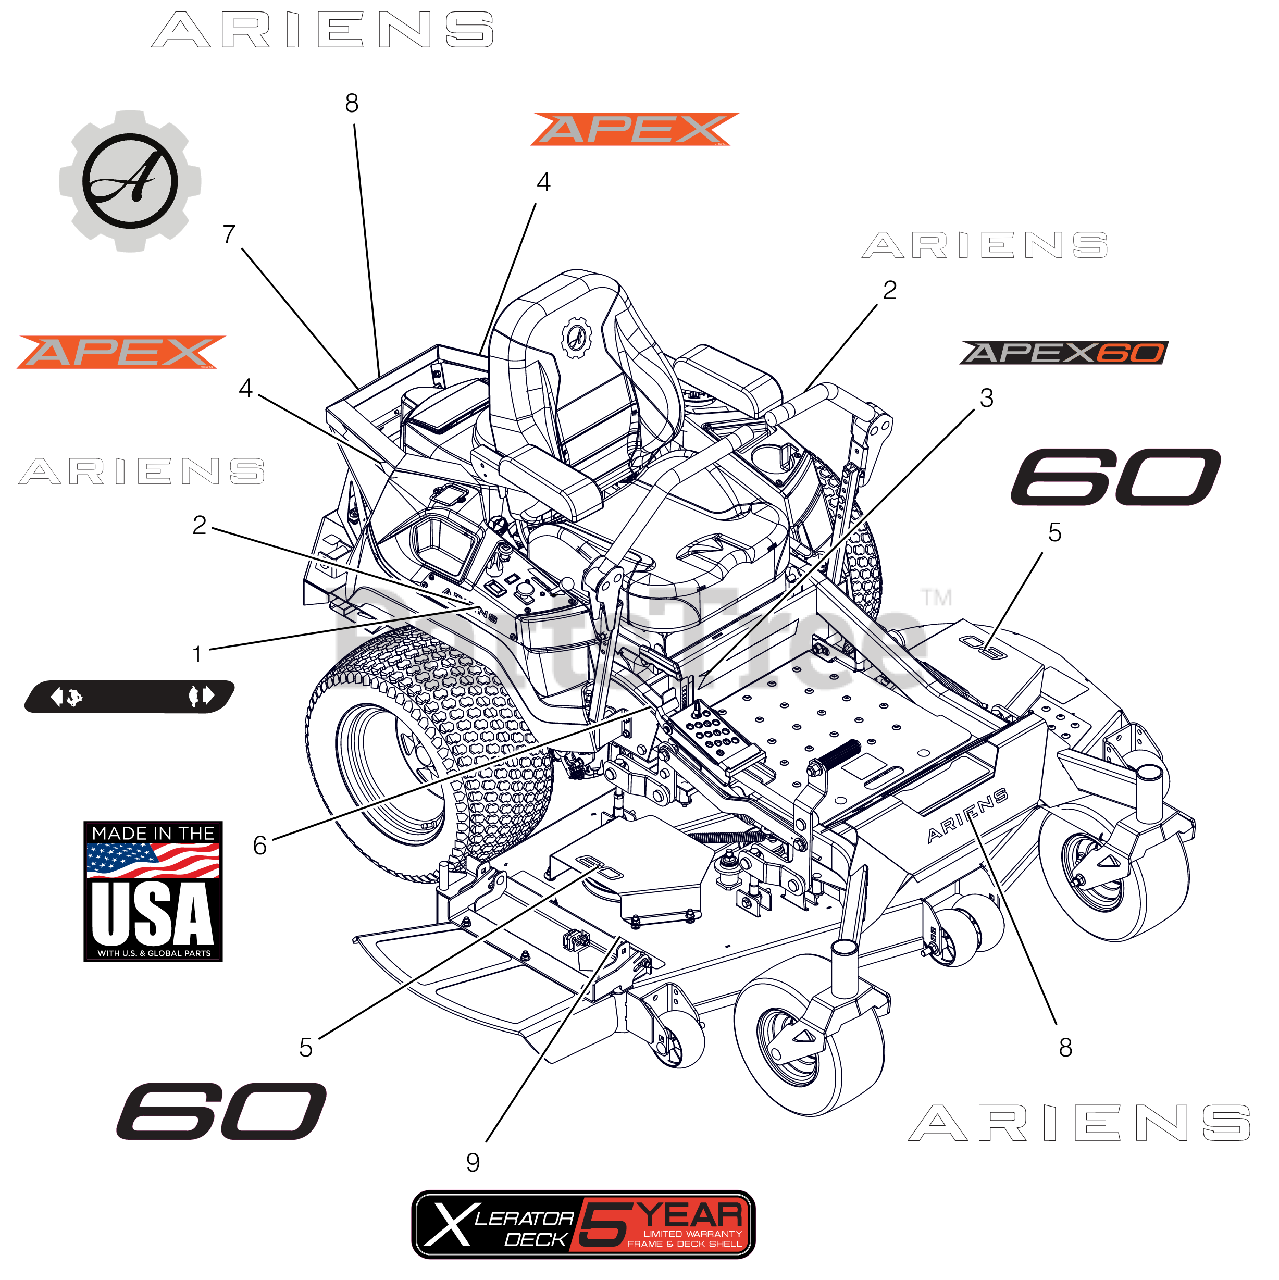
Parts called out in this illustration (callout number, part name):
1	DECAL, DASH DECAL
2	DECAL, ARIENS (6.50")
3	DECAL, 60" APEX KICKPLATE
4	DECAL, APEX FENDER
5	DECAL, BLACK 60
6	DECAL, MADE IN USA
7	DECAL, ARIENS-GEAR BADGE -THK
8	DECAL - ARIENS 9.625"
9	DECAL-ARIENS, DECK 5 YEAR
